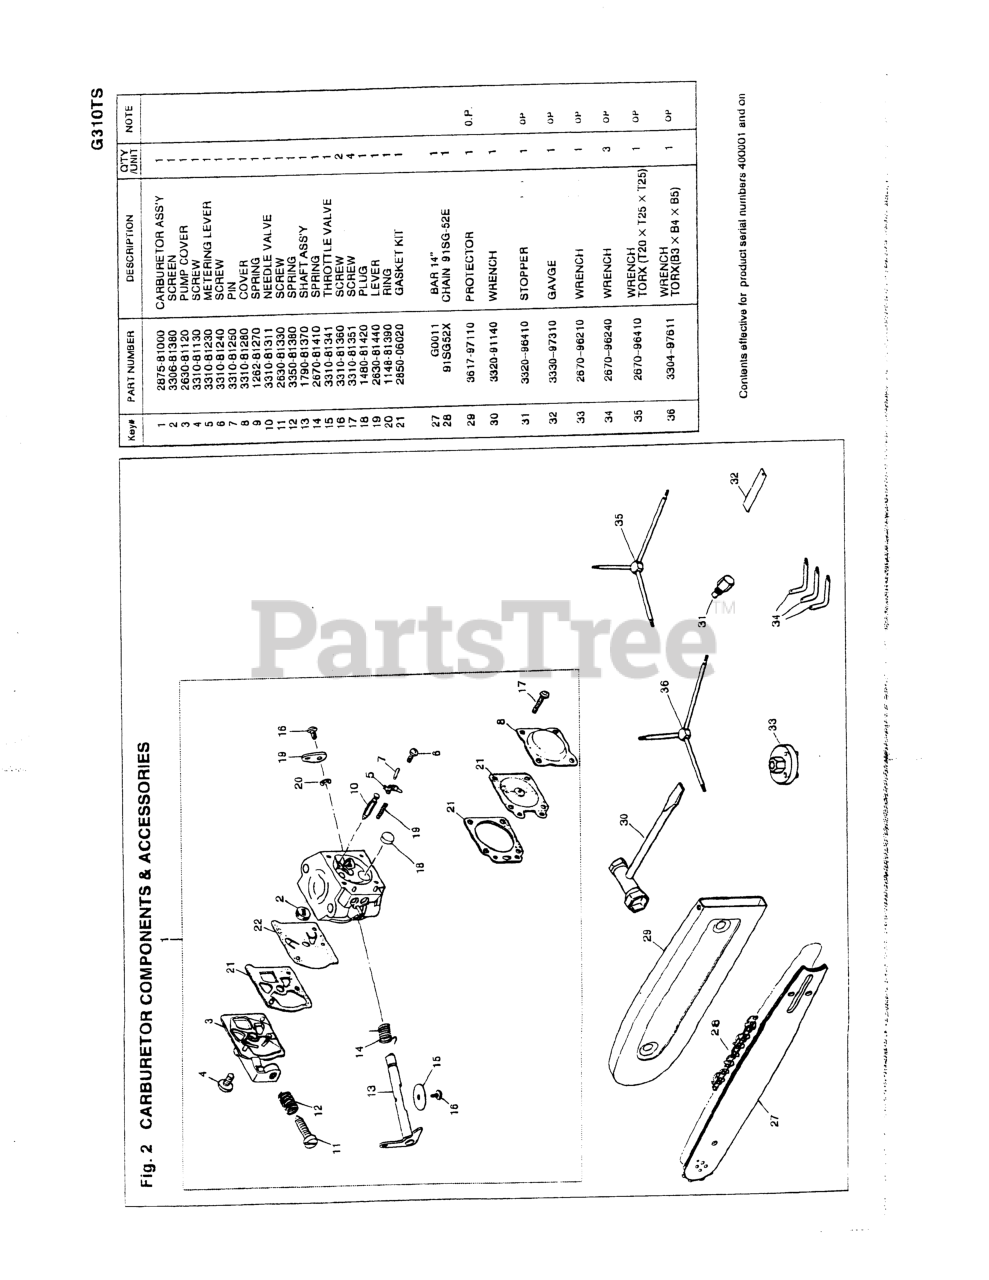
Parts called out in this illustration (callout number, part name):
1	CARBURETOR (USE 2875-81001)
5	LEVER
7	PIN, METERING LEVER
9	KIT ONLY
12	SPRING, IDLE
13	SHAFT, THROTTLE
14	SPRING, RETURN
17	SCREW ASSEMBLY
18	PLUG, WELSH
27	BAR 14
29	PROTECTOR (14.5
30	WRENCH, PLUG
32	GAUGE (TOOL)
33	WRENCH (TOOL)
34	WRENCH (TOOL)
36	HEX WRENCH (TOOL)
